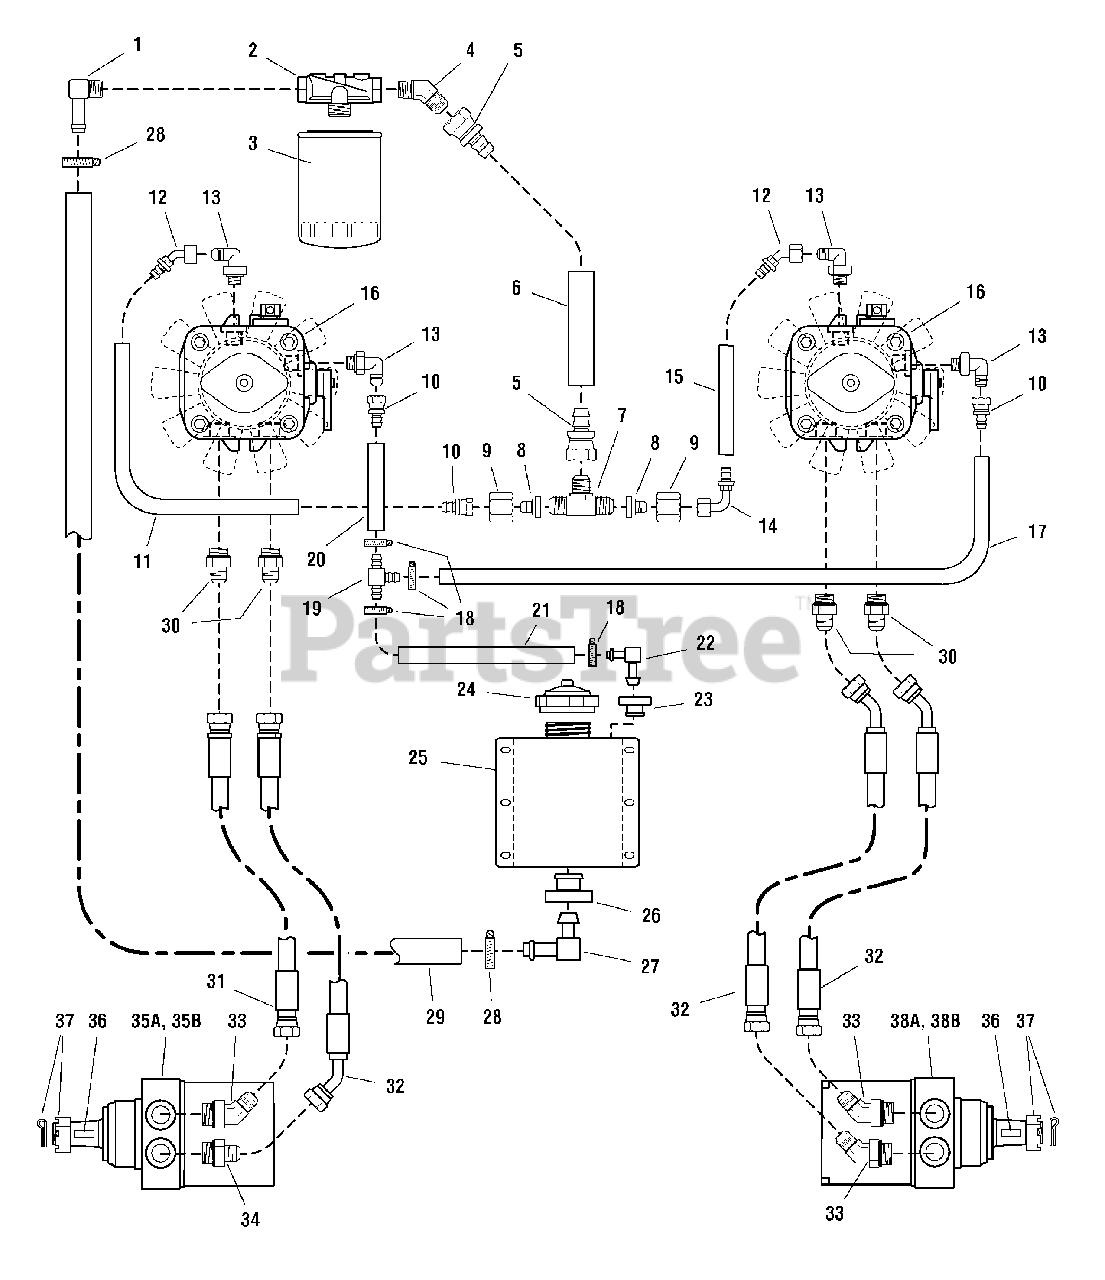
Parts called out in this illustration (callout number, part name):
1	FITTING, 1/2" NPT, 90 Deg.
2	FILTER HEAD
4	FITTING, 1/2" NPT, 45 Deg.
5	FITTING, Hydraulic, Straight Swivel
6	HOSE, Hydraulic, 7-1/2"
7	FITTING, Tee
8	ADAPTER, Tee
9	NUT, Adapter
10	FITTING, Hydraulic, Straight Swivel
11	HOSE, Hydraulic, 13-3/4"
12	FITTING, Hydraulic, 45 Deg. Swivel
13	FITTING, Hydraulic, O-Ring, 90 Deg.
14	FITTING, Hydraulic, 90 Deg. Swivel
15	HOSE, Hydraulic, 6-3/4"
16	HYDRAULIC PUMP w/ FAN
17	HOSE, Hydraulic, 16-1/2"
18	HOSE CLAMP, #6
19	FITTING, TEE, 3/8"
20	HOSE, Hydraulic, 6"
21	HOSE, Hydraulic, 17-1/2"
22	FITTING, Elbow, 3/8"
23	GROMMET
25	HYDRAULIC OIL RESERVOIR, Complete (includes Ref. No. 22, 23, 26 & 27)
27	FITTING, Elbow, 5/8"
28	HOSE CLAMP, #10
29	HOSE, 5/8" PUSH-ON, 22.00"
30	FITTING, Hydraulic, O-Ring Adapter
31	HYDRAULIC HOSE ASSEMBLY, 21"
32	HYDRAULIC HOSE ASSEMBLY, 25"
33	FITTING, Hydraulic, O-RIng, 45 Deg.
34	FITTING, Hydraulic, O-Ring Adapter
35A	HYDRAULIC WHEEL MOTOR-LEFT, Complete (includes Ref No. 36 & 37)(ZT2148T - S/N: 678 & below)(ZT2352T - S/N: 835 & below)
35B	HYDRAULIC WHEEL MOTOR-LEFT, Complete (includes Ref No. 36 & 37)(ZT2148T - S/N: 679 & above)(ZT2348T - all)(ZT2352T - S/N: 836 & above)
37	NUT & COTTER PIN
38A	HYDRAULIC WHEEL MOTOR-RIGHT, Complete (includes Ref No. 36 & 37)(ZT2148T - S/N: 678 & below)(ZT2352T - S/N: 835 & below)
38B	HYDRAULIC WHEEL MOTOR-RIGHT, Complete (includes Ref No. 36 & 37)(ZT2148T - S/N: 679 & above)(ZT2348T - all)(ZT2352T - S/N: 836 & above)
